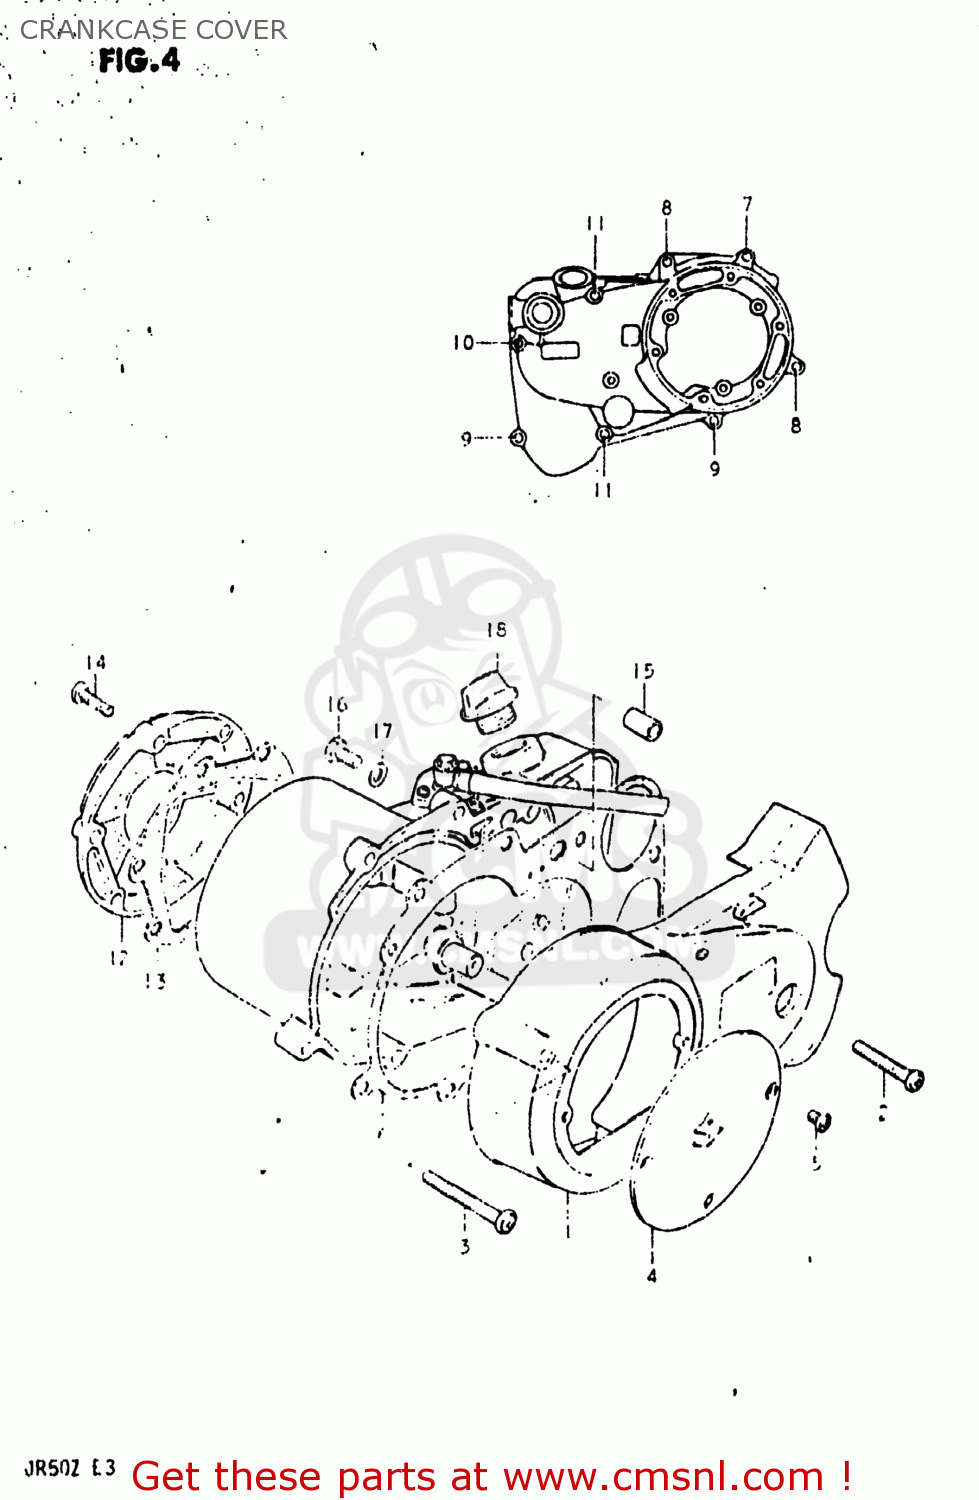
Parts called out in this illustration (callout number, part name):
1	COVER,MAGNETO
2	SCREW (6X35)
3	SCREW (6X45)
4	CAP,MAGNETO INSPECTION
5	SCREW 4X6
6	GASKET,CLUTCH COVER (MCA)
7	SCREW
8	SCREW
9	SCREW 6X30
10	SCREW (6X45)
11	SCREW
12	CAP,CLUTCH RELEASE ADJUST
13	GASKET,CLUTCH RELEASE ADJUSTER CAP (NAS)
14	SCREW
15	PIN
16	SCREW(6X10)
17	GASKET(6.2X11X1) (NAS)
18	PLUG,OIL FILTER
